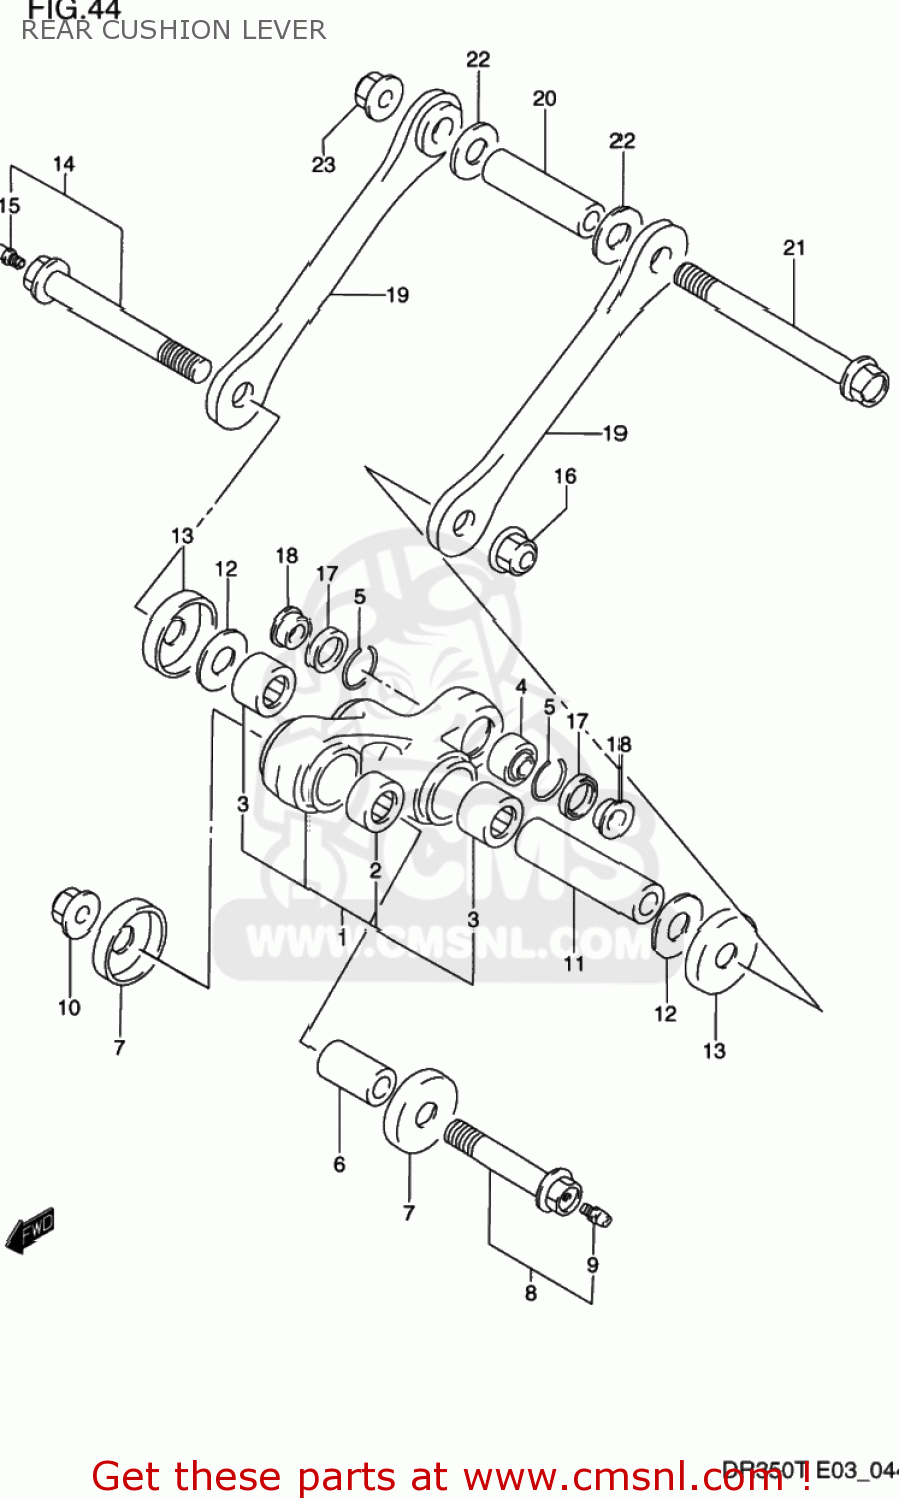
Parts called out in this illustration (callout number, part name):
1	LEVER SET,RR CUSHION
2	BEARING(20X27X32)
3	BEARING(20X27X23.5)
4	BEARING,RR CUSHION LEVER
5	RING,STOPPER
6	SPACER,RR CUSHION LEVER FR
7	SEAL,REAR CUSHION LEVER
8	BOLT,RR CUSHION LEVER FR
9	GREASE NIPPLE
10	NUT 12MM
11	SPACER,RR CUSHION LEVER CTR
12	WASHER
13	SEAL,RR CUSHION LEVER
14	BOLT,RR CUSHION LEVER CTR
15	GREASE NIPPLE
16	NUT
17	SEAL,OIL(17X24X3)
18	COLLAR
19	ROD,RR CUSHION
20	SPACER,RR CUSHION ROD
21	BOLT,RR CUSHION ROD
22	WASHER
23	NUT
